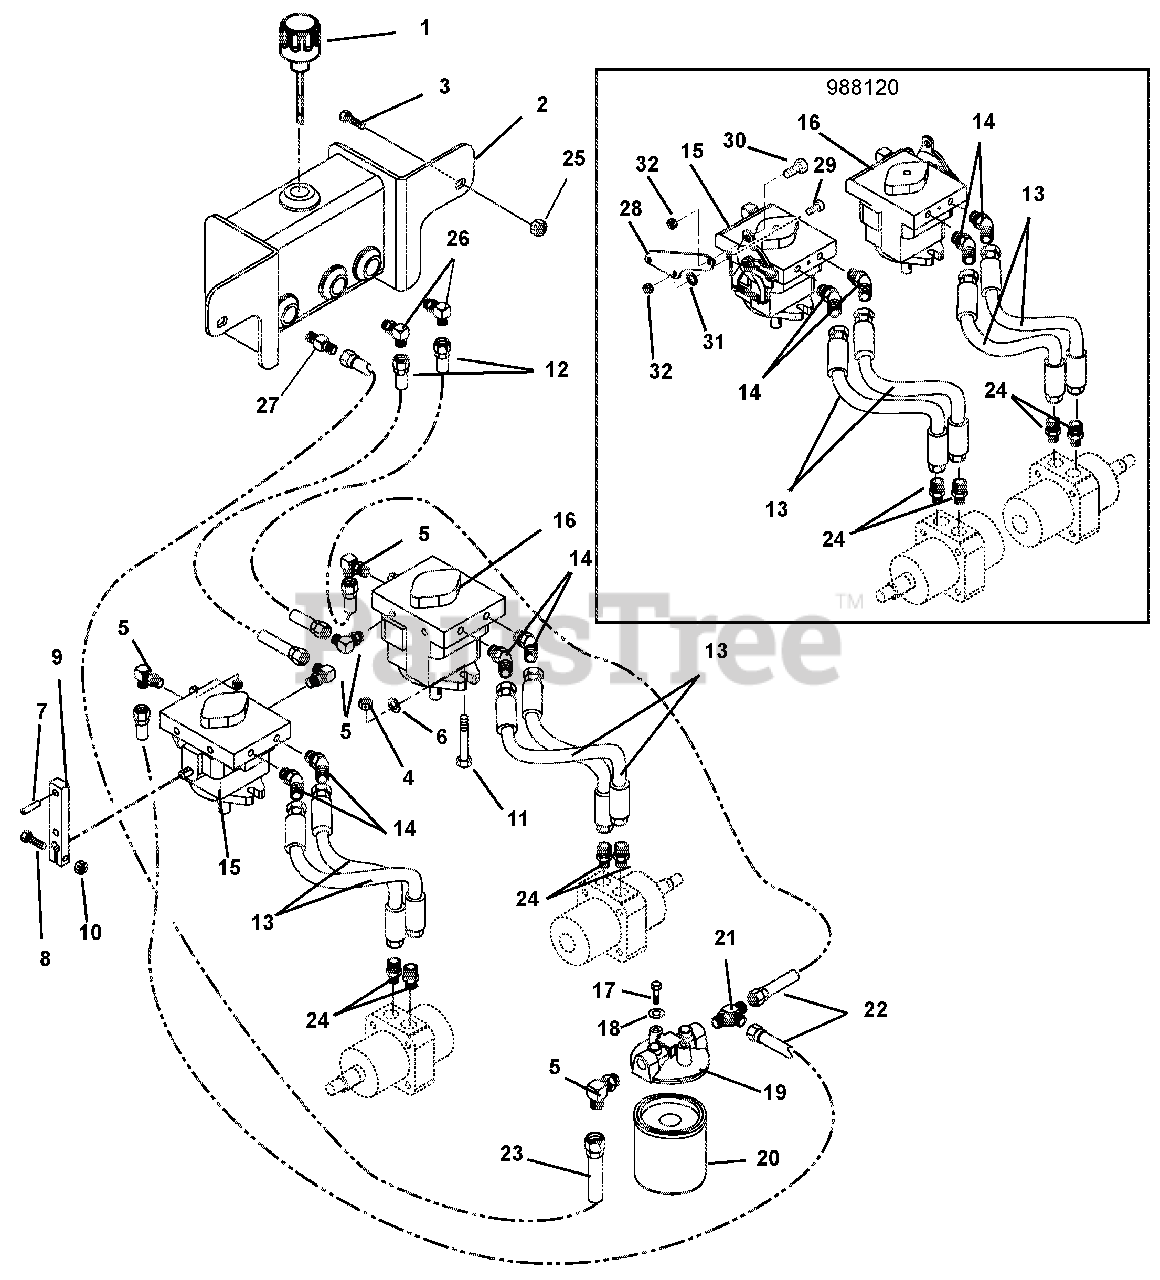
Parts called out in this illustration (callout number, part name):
1	Breather, Dipstick
2	Tank Assembly, Hydraulic
3	Bolt-Hex .38-16 x 1.00 Grade 5
4	Nut-Nylon-Locking .44-14
5	Fitting, Hydraulic
6	Washer-Flat-Steel .43 x 1.00 x .16
7	Pin-Dowel .312 x 1.25 (105, 108, 123, 126)
8	Bolt-Hex .25-20 x 1.25 Grade 5 (105, 108, 123, 126)
9	Arm, Pump Actuating (105, 108, 123, 126)
10	Nut-Locking-Nylon .25-20 (105, 108, 123, 126)
11	Bolt-Hex .44-14 x 1.50 Grade 5
12	Hose, Hydraulic
13	Hose, Hydraulic
14	Fitting, Hydraulic
15	Pump, Hydraulic Right Hand (105, 108, 123, 126)
15	Pump, Hydraulic Right Hand w/ Return (120, 124, 125, 127)
16	Pump, Hydraulic Left Hand (105, 108, 123, 126)
16	Pump, Hydraulic Left Hand w/ Return (120, 124, 125, 127)
17	Bolt-Hex .25-20 x .50 Grade 5
18	Washer-Locking .25 x .062 Regular
19	Head, Filter
20	Filter- Oil
21	Fitting, Hydraulic Tee
22	Hose, Hydraulic
23	Hose, Hydraulic
24	Fitting 12MP-6FP BROYHILL# TM5406-12-6
25	Nut-Locking-Nylon .38-16
26	Hydraulic, Fitting Elbow
27	Hydraulic, Fitting Straight
28	Bracket, Return to Neutral/Damper (120, 124, 125, 127)
29	Bolt-Hex .31-18 x .50 Grade 5 (120, 124, 125, 127)
30	Bolt-Hex .31-18 x 1.00 Grade 5 (120, 124, 125, 127)
31	Bushing-Sleeve .377 x .624 x .370 (120, 124, 125, 127)
32	Nut-Locking-Center .31-18 (120, 124, 125, 127)
